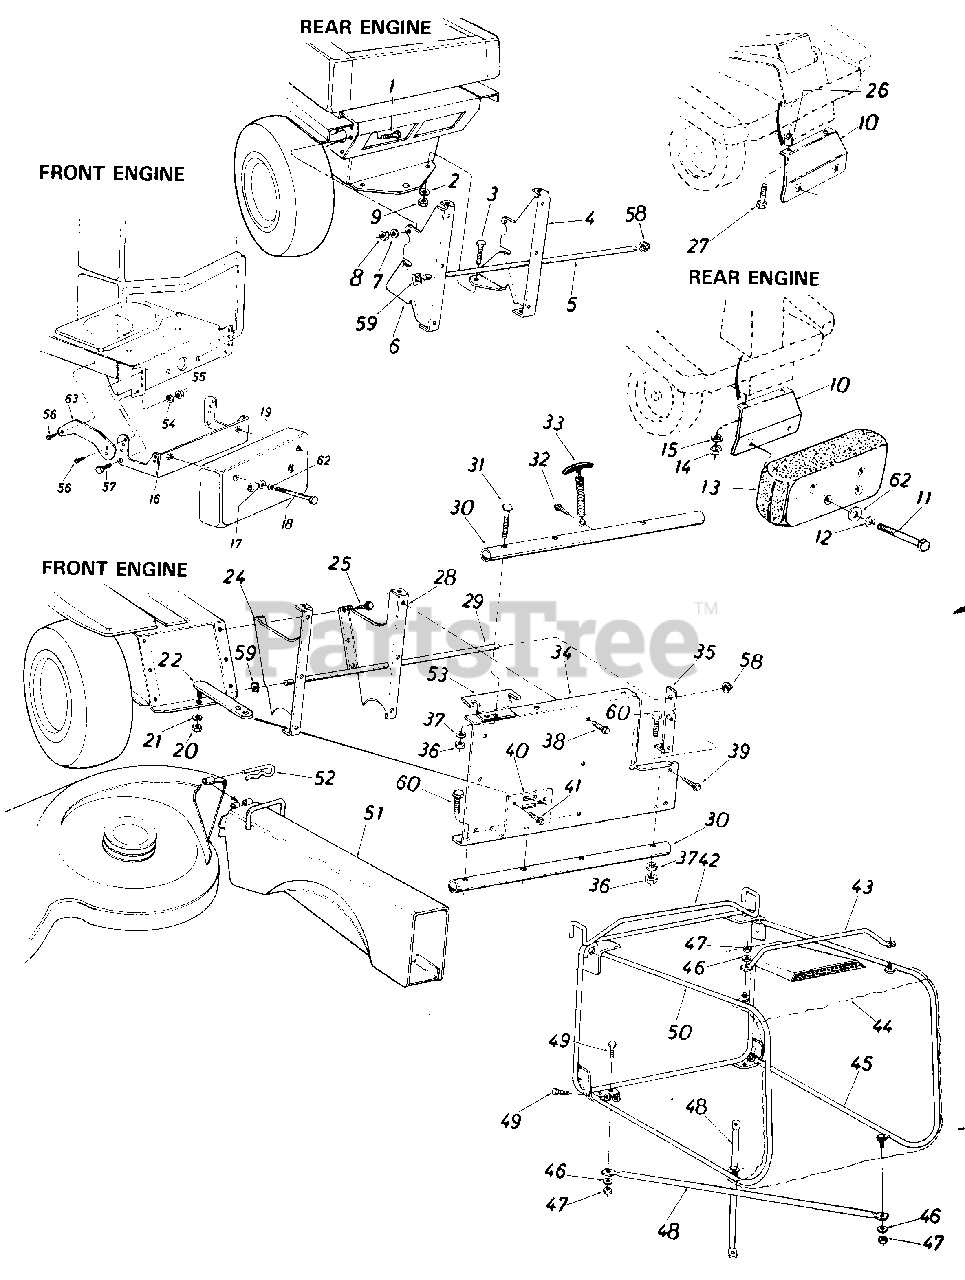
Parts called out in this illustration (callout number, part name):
1	Hex Bolt 5/16-18 x 1.00" Lg.*
2	L.-Wash. 5/16" I.D.*
3	Hex Bolt 5/16-18 x 1.00" Lg.*
4	Catcher SupportBrkt-R.H.
7	L.-Wash. 5/16" I.D.*
8	Hex Nut 5/16-18 Thd.*
9	Hex Nut 5/16-18 Thd.*
10	Counterweight Bracket
11	Hex Bolt 3/8-16 x 4.5" Lg.*
12	Belleville Wash. .400 I.D. x .88" O.D.
13	Front Counterweight 38Lbs
14	Hex Nut 5/16-18 Thd.*
15	L.-Wash. 5/16" I.D.*
16	Counterweight Bracket
17	Belleville Wash. .400" I.D. x.88" O.D.
18	Hex Bolt 3/8-16 x 4.5" Lg.*
19	Front Counterweight 38 Ibs.
20	Hex Jam Nut 1/2-13 Thd.*
21	L.-Wash. 1/2" I.D.*
25	Hex Wash. Hd. Self Tap Scr. 5/16-18 x .75 Lg.*
26	Spacer.380" I.D. x 1.00" O.D. x.320" Lg.
27	Not Part of Kit
28	Catcher Support Brk t.-R.H.
31	Curved Carriage Bolt 5/16-18 x 1.75" Lg.
32	Hex "AB"-Tap Scr. 1/4" x 62" Lg.
33	Hood Latch Ass'y.
34	Grass Catcher Adapter
35	Grass Catcher Support Brk't. - R.H.
36	Hex Nut 5/16-18 Thd.*
37	L.-Wash. 5/16" I.D.*
38	Hex Wash. Hd. Self Tap Scr. 1/4-20 x .50" Lg.
39	Hex Wash. Hd. Self Tap Scr. 1/4-20 x .50" Lg.
40	Hitch Bracket
41	Hex Wash. Hd. Self Tap Scr. 1/4-20 x .50" Lg.
42	Grass Bag Frame Ass'y.
43	Grass Catcher Handle 26.75
44	G rass Catcher Bag
47	Hex L.-Nut 1/4-20 Thd.
48	Bottom Cross Brace 30.36" Lg.*
49	Hex Bolt 1/4-20 x .62" Lg.*
52	Not Part of Kit
53	Grass Catcher Support Plate
54	L.-Wash. 7/16" I.D.*
55	Hex Nut 7/16-20 Thd.*
56	Hex AB Tap Scr. 5/16-18 x l" Lg.
57	Hex Bolt 7/16-20 x 1.00" Lg.*
58	Push Cap
59	Speed Nut
60	Hex Bolt 5/16-18 x 1.75" Lg.*
62	Fl.-Wash. .390" I.D. x 1.12" O.D. x .187 Thk.
63	Tie Strap
